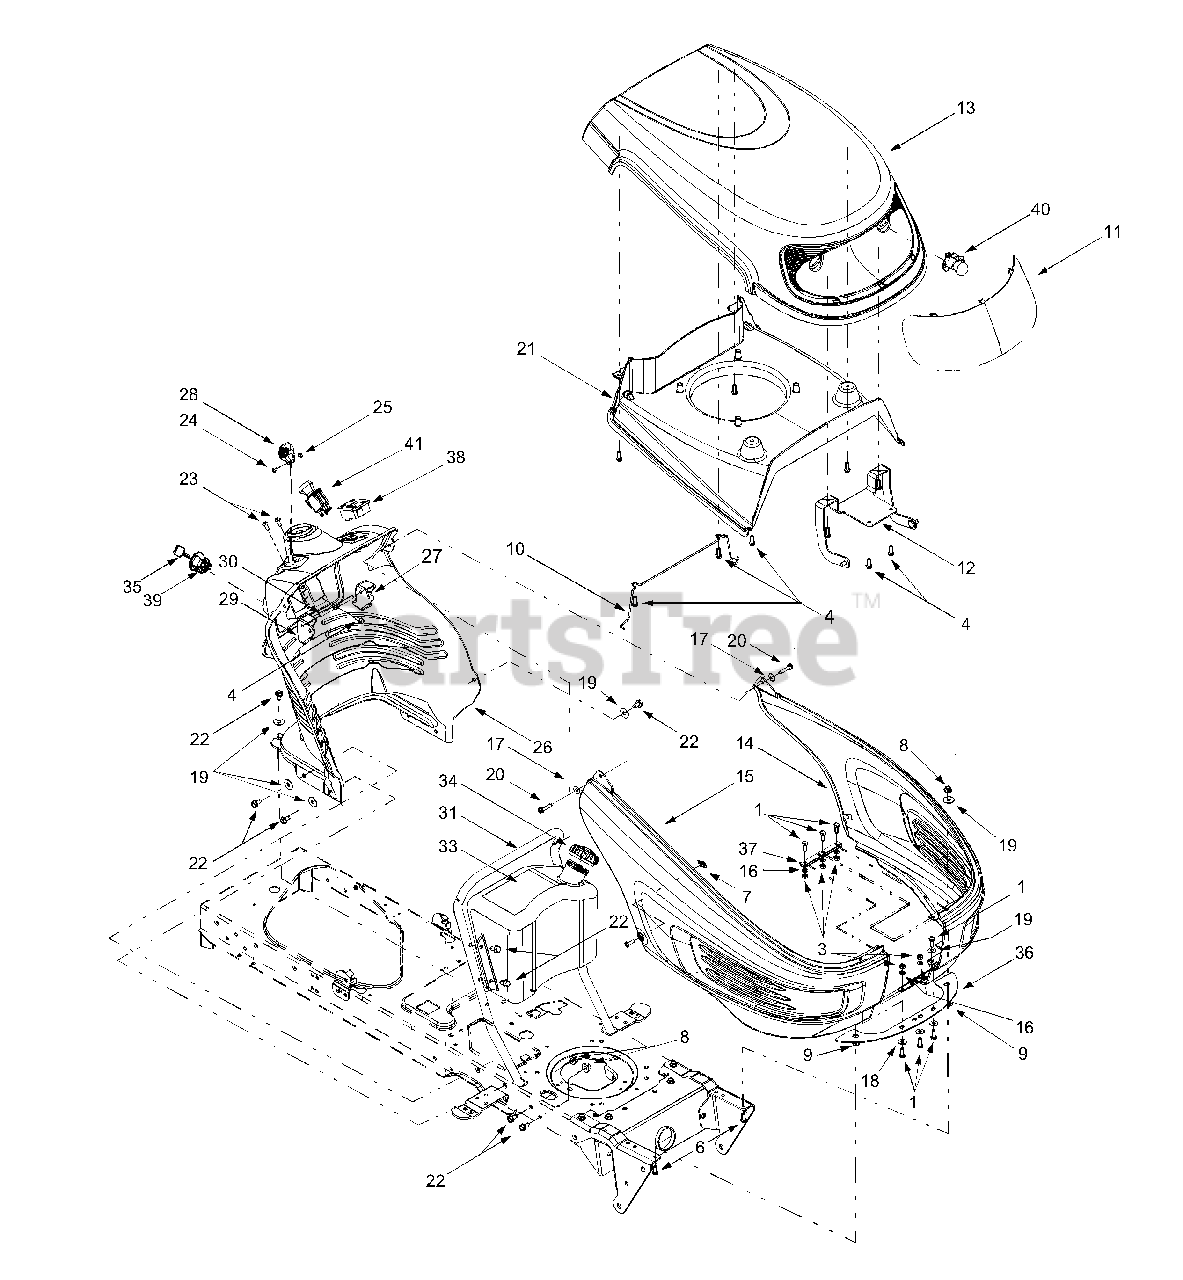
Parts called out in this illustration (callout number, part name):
1	Hex Cap Screw, 1/4-20 x .75
3	Hex Nut, 1/4-20
4	Self-tapping Screw, 1/4-15 x .75
6	Hex Cap Screw, 5/16-18 x 1.25
7	U-type Speed Nut, 1/4-20
8	Flange Lock Nut, 5/16-18
10	Hood Latch Rod
11	Head Light Lens
14	LH Side Panel
15	RH Side Panel
16	Lock Washer, 1/4
17	Flat Washer, .283 x .75 x .030
18	Flat Washer, .28 x .74 x .063
19	Flat Washer, .349 x 1.0 x .063
20	Self-tapping Screw, 1/4-20 x 1.25
22	Self-tapping Screw, 5/16-18 x .625
23	Torx Self-tapping Screw, 1/4-14 x .625
24	Torx Screw, #8-32 x .375
25	Hex Nut, 8-32
26	Dash Panel, 4-style
27	Parking Brake Button
28	Throttle Control Lever
29	Cruise Control Button
30	Brake/Cruise Pivot Rod
33	Fuel Tank, 2-gallon
34	Fuel Cap (Fits both tanks)
35	Ignition Key w/ plastic cover
39	Ignition Switch
40	Headlight Assembly
41	Electric PTO Switch
